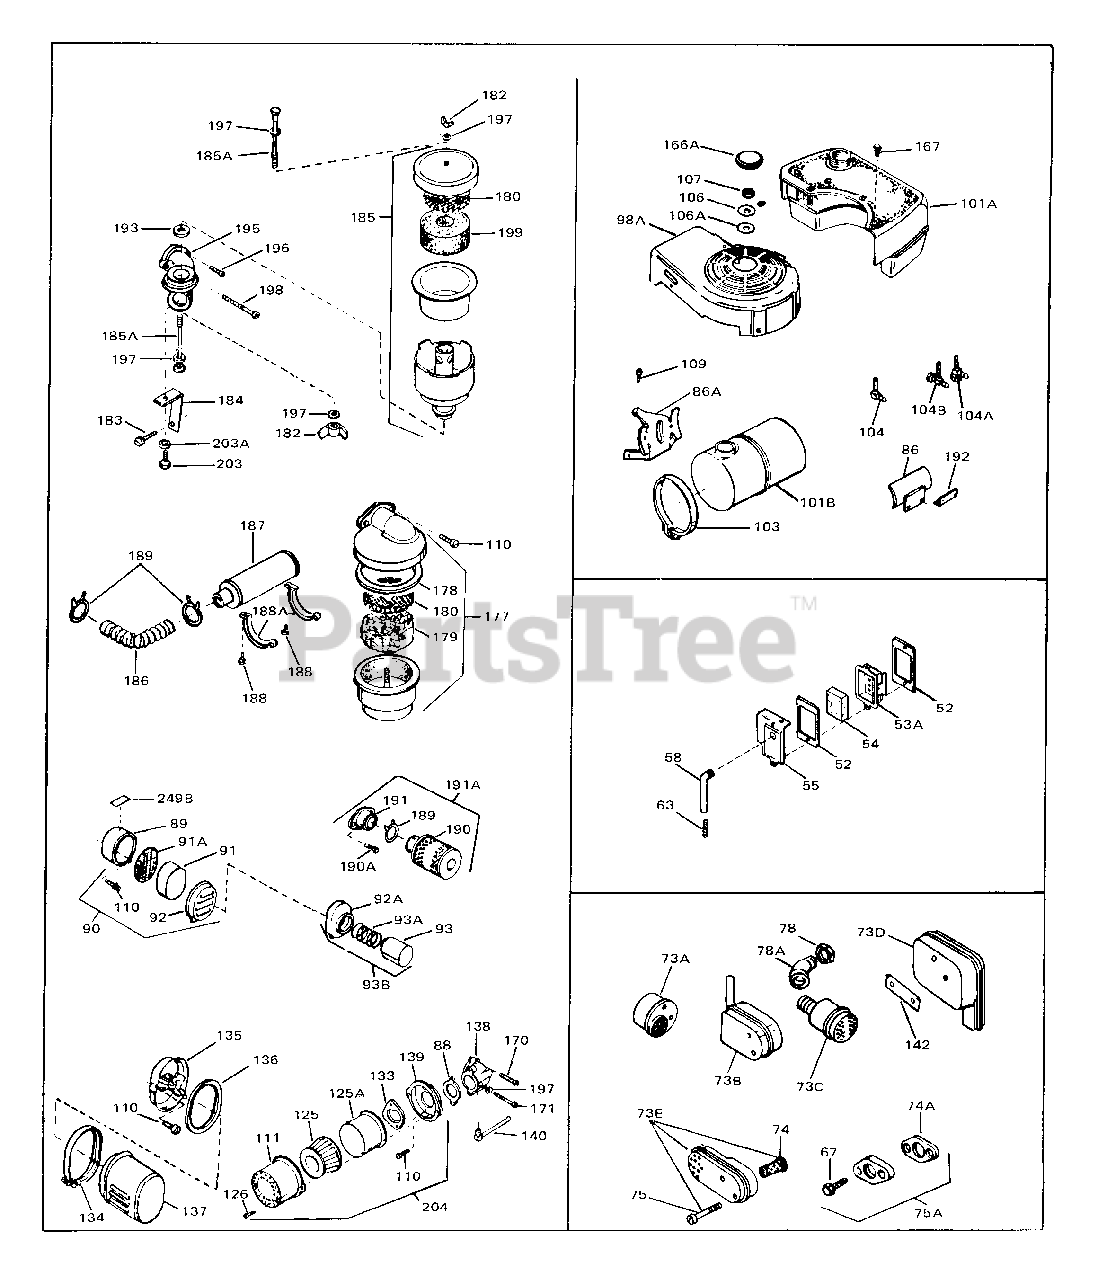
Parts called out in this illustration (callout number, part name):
52	Gasket, Breather cover
63	Spring, Breather tube
67	Screw, Phil. fil. hd. Sems 1/4-20 x 9 /16
74A	Gasket, Exhaust
75	Screw, Hex hd. cap, 1/4-20 x 3-3/8
75	Screw, Hex hd. cap, 1/4-20 x 2-1/2
75	Screw, Hex hd. cap, 1/4-20 x 3
75	Screw, Hex hd. cap, 1/4-20 x 2-3/4
75	Screw, Hex hd. cap, 1/4-20 x 2-1/4
75	Screw, Hex hd. Sems, 1/4-20 x 1-3/4
75	Screw, Hex hd. cap, Sems, 1/4-20 x 2- 5/16
75A	Kit, Muffler Adapter
78	Nut, Conduit
78A	Elbow, Exhaust (90(deg))
78A	Elbow, Exhaust (45(deg))
88	Gasket, Air cleaner
89	Body, Air cleaner
90	Cleaner Assy., Air
91	Element, Air cleaner
91A	Screen, Air cleaner
92	Cover, Air cleaner
93	Bag, Pre-cleaner
93A	Spring, Pre-cleaner
93B	Kit, Pre-cleaner
104	Fitting, Fuel strainer & Elbow
104A	Strainer & Shut-off Valve, Fuel
104B	Valve, Fuel shut-off
106	Washer, Belleville
107	Nut, Flywheel
109	Screw, Phil. hex hd. Sems, 1/4-20 x 5 /8
110	Screw, Phil. fil. hd. mach. Sems, 10- 32 x
110	Screw, Phil. fil. hd. Sems, 10-32 x 1 -5/8
110	Screw, Phil. fil. hd. Sems, 10-32 x 5 /8
126	Screw, Fit. slotted hd. Sems, 8-32 x 3/8
133	Spacer, Cleaner
140	Fitting, Breather
170	Screw, Fit. slotted hd. Sems, 10-32 x 3/4
171	Screw, Phil. fit. hd. mach., 10-32 x 2-1/2
182	Nut, Wing, 10-24
183	Screw, Slotted hex washer hd., 1/4-20 x 7/16
184	Bracket, Cleaner elbow
191A	Air Cleaner Kit
192	Bracket, Housing
193	Gasket, Air cleaner
196	Screw, Fil. slotted hd. Sems, 10-32 x 3/4
197	Washer, Fiber
197	Washer, Paper
198	Screw, Phil. fil. hd. mach., 10-32 x 2-7/8
198	Screw, Phil. fil. hd. mach., 10-32 x 2-1/2
199	Element, Air cleaner
203	Screw, Hex hd. cap, Sems, 1/4-20 x 1/ 2
203A	Lockwasher, 1/4
204	Cleaner Assy. (Poly)
249B	Decal, Air cleaner
